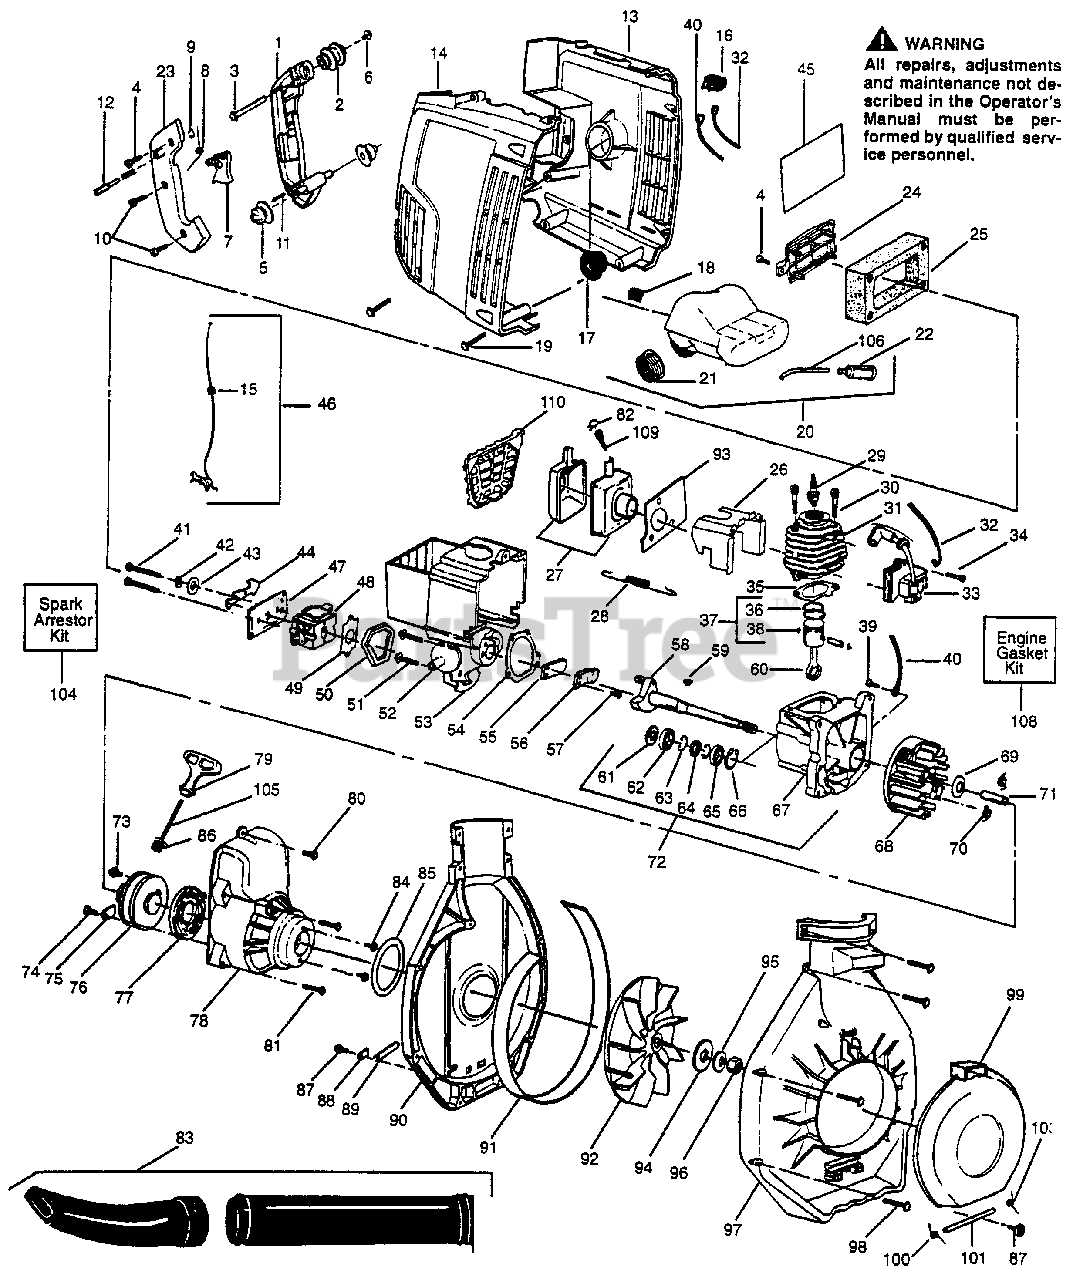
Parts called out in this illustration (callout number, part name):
1	Handle
2	Front isolator
4	Screw-Handle
5	Rear Isolator
10	Throttle Lock Button
13	Shroud-Left
14	Shroud-Right
16	Switch Kit
17	Isolator-Engine Mount
18	Isolator-Tank
19	Screw-Shroud
20	Fuel Tank Ass'y.
21	Fuel Cap Ass'y.
22	Fuel Pick-up Ass'y.
23	Handle Cover Ass'y.
24	Cover-Ar Filter
25	Air Filter
26	Air Baffle
27	Muffler Kit
28	Spring-Muffler
29	Spark Plug (RCJ-8Y)
30	Screw-Cylinder
31	Cylinder Kit
33	Ignition Module
34	Screw-Ignition Module
35	Gasket-Cylinder
36	Piston Ring
37	Piston Kit
39	Screw-Groundwire
40	Ground Wire
42	Wave Washer
44	Choke Shutter
45	Instruction Decal
46	Cable Assembly
48	Carburetor (WT 141A) w/Limiter Cap
49	Gasket-Carburetor
50	Seal-Reed Block
51	Screw-Reed Block
52	Ground Wire
53	Reed Block/Heat Shield
54	Gasket-Reed Block
55	Reed Valve
57	Screw
58	Crankshaft
59	Key-Flywheel
60	Connecting Rod Ass'y.
61	Spacer
62	Inner Bearing
63	Ring-Retaining, C'case
64	Crankshaft Seal
65	Outer Bearing
66	Retaining Ring-Crankshaft
67	Crankcase Ass'y.
70	Spring-Starter Dog
71	Spacer-Flywheel
72	Crankcase/Crankshaft Assy.
73	Screw-Starter Pulley
74	Screw-Retainer
76	Starter Pulley
77	Starter Spring
78	Fan Housing Kit
79	Starter Handle
80	Screw-Fan Housing
81	Screw-Fan Housing
83	Tube and Nozzle As'y.
84	Screw-Fan Housing
85	"O" Ring-Fan Housing
89	Tube-Rope Retainer
90	Blower Housing (Upper)
92	Impeller Ass'y.
93	Muffler Gasket
94	Washer-Impeller
95	Washer-Conical
97	Blower Housing (Lower) Ass'y
100	Spring-Right
103	Spring-Left
104	Spark Arrestor Kit
108	Gasket Kit
110	Muffler Guard
